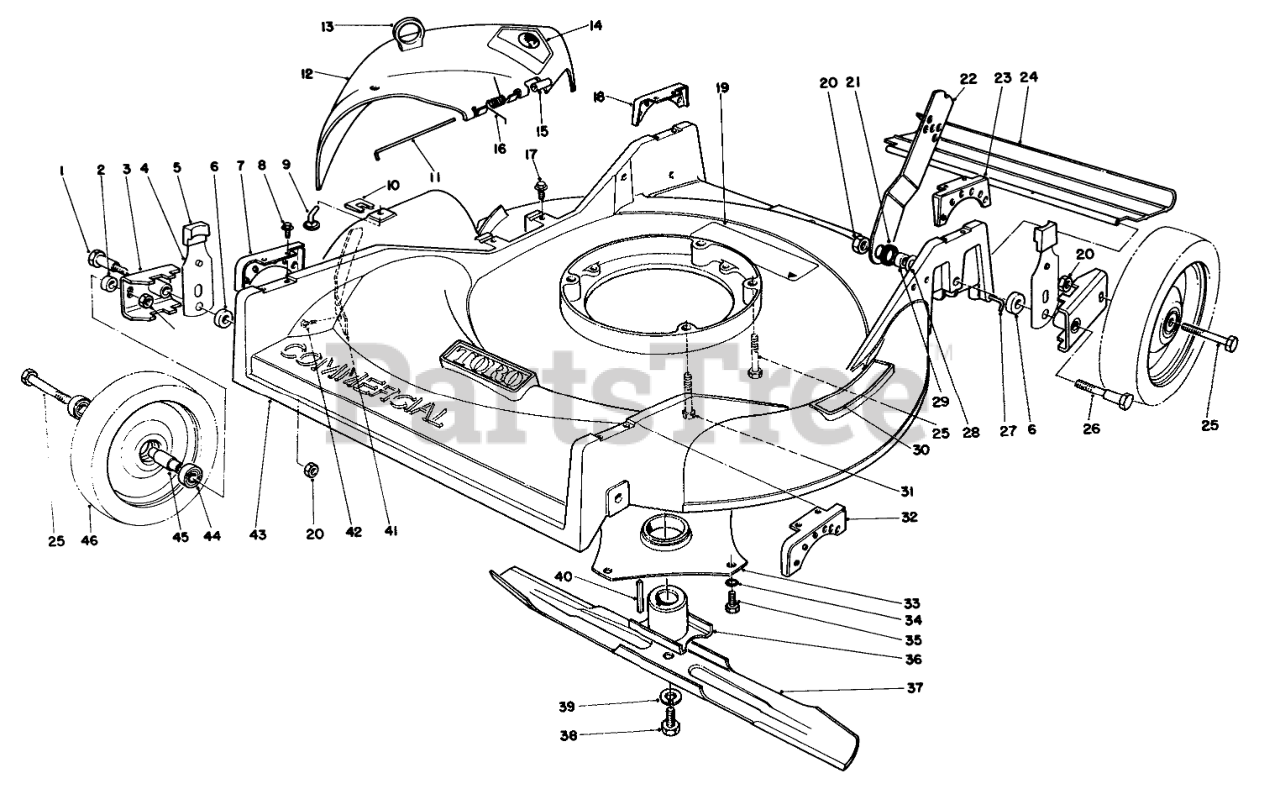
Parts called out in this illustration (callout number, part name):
1	PIVOT SCREW
2	SPACER-WHEEL
3	PIVOT ARM
4	SPRING ARM ASM-FRONT
5	KNOB-ARM
6	PIVOT ARM SPACER
7	FRT RIGHT QUAD
8	Screw
9	BAG CHUTE PIN
10	BAG CHUTE CLIP PIN
11	DEFLECTOR HINGE PIN
12	Deflector
13	LIFT LOOP
14	DECAL-DANGER
15	SLEEVE
16	DEFLECTOR SPRING
17	SCREW
18	REAR RIGHT QUAD
19	DECAL SAF INST
20	NUT-LOCK, NI
21	HANDLE LATCH SPACER
22	Latch-Handle
23	REAR LEFT QUAD
24	SHIELD - TRAILING
25	SCREW-HH
26	REAR PIVOT SCREW
27	SHIELD ROD
28	WASHER-BELLEVILLE
29	HANDLE LATCH SPACER
30	STEP PAD DECAL
31	SCREW-HH
32	FRT LEFT QUAD
33	CRNKSHFT PROTECT ASM
34	WASHER-LOCK, INTERNAL
35	SCREW-HWHTF
36	RETAINER-BLADE
37	Blade
38	BLADE SCREW
39	WASHER-LOCK
40	KEY-SQUARE
41	Bar Safety
42	SCREW THD 1/4 20 5/8
43	Housing
44	BEARING-WHEEL
45	SPACER-BEARING
46	Wheel & Tire Assembly (Incl. Ref. #44 & 45)
